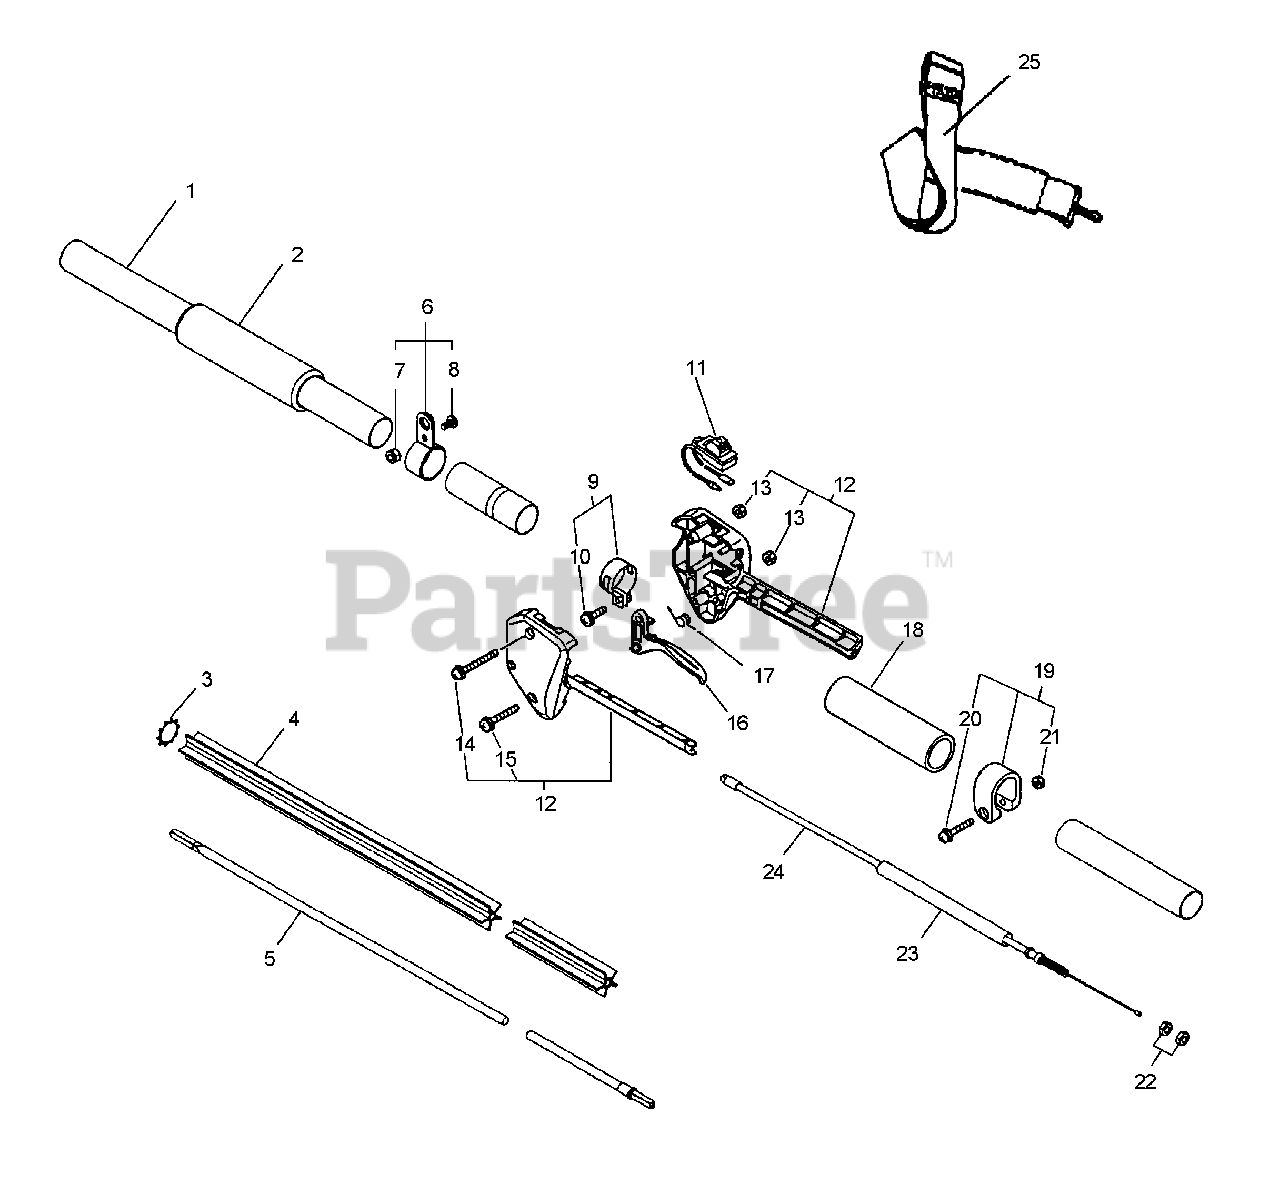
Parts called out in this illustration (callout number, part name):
1	MAIN PIPE ASSY
2	GRIP, FRONT - LEFT
3	LOCKWASHER - EXTERNAL
4	LINER - FLEXIBLE
5	DRIVESHAFT - FLEXIBLE
6	HANGER KIT
7	LOCKNUT - 10-24
8	SCREW
9	CLAMP KIT
10	SCREW - 5X14
11	IGNITION SWITCH ASSY
12	CONTROL HANDLE KIT
14	SCREW - 5X35
15	SCREW - 5X25
16	TRIGGER, THROTTLE
17	SPRING, TRIGGER
18	GRIP, HANDLE
19	CLAMP KIT
20	SCREW - 5X28
23	TUBE - VINYL
24	CABLE, THROTTLE
25	SHOULDER STRAP ASSY
